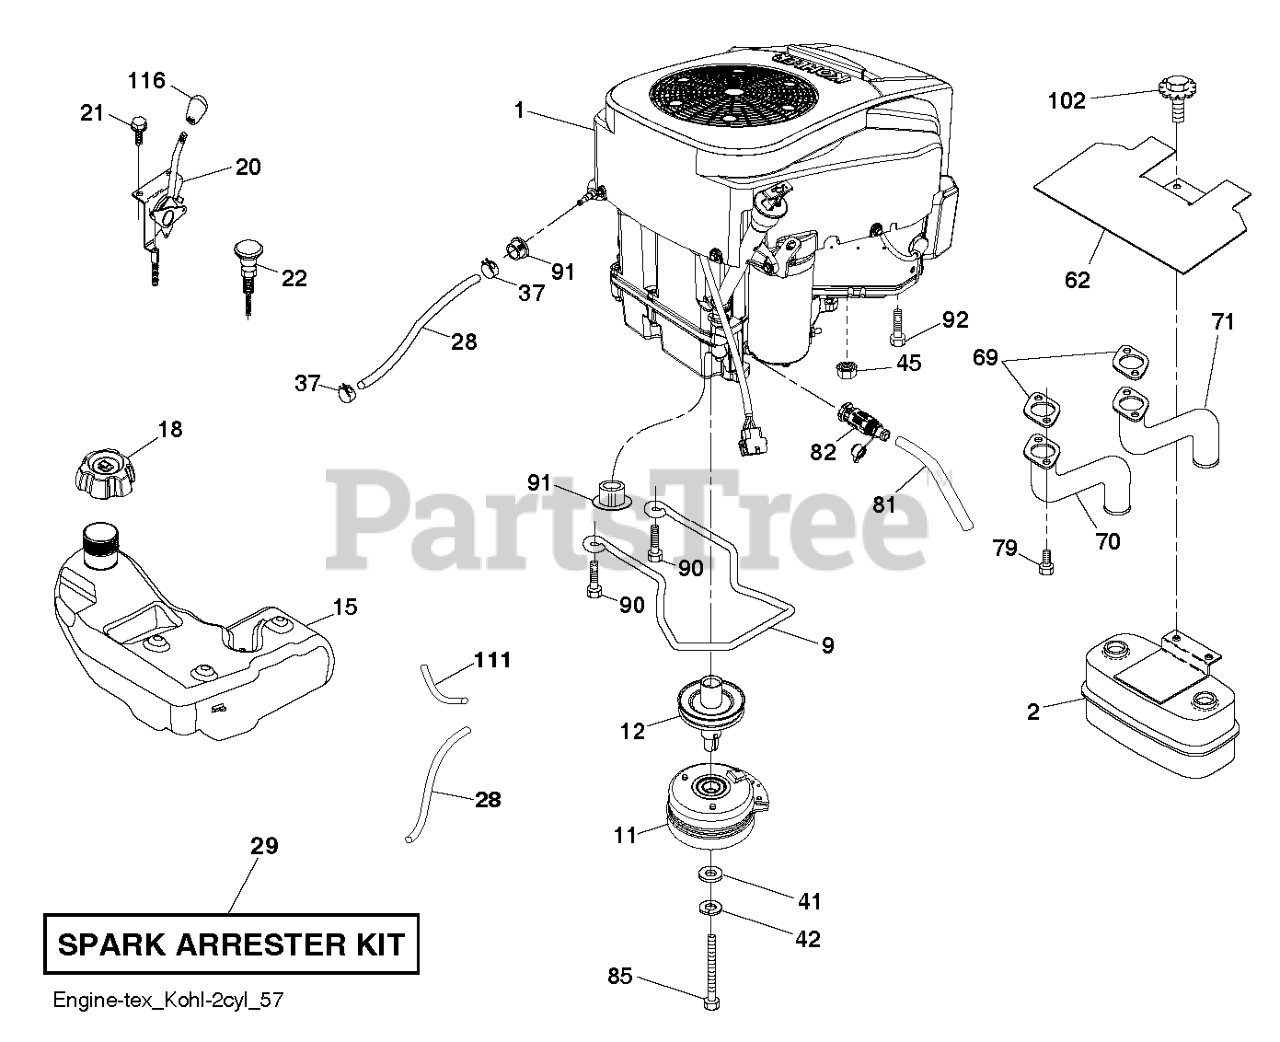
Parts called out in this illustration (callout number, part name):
2	MUFFLER.ASM.TWN.EXTNDED.DFLCTR
9	KEEPER.BELT.ENGINE.4.2
11	CLUTCH. 5.0 PD. 2.5 OFFSET
12	PULLEY.EXTENDED.SHAFT.GROUND
15	TANK.ASM.FUEL.3GA.CARB
18	CAP ASSY FUEL 3" GRAY
20	CONTROL.THROTTLE.PRO.KOHLER
21	SCREW.#10 X 0.750.BOS
22	CONTROL, CHOKE
28	LINE.FUEL.64"REAR.EMIS
29	KIT.SPARK ARRESTOR 794945 B&S
37	HOSE CLAMP
42	LOCKWASHER
45	NUT
62	SHIELD.HEAT.MUFFLER
70	TUBE.EXHAUST.LH.FR961/FR730
71	TUBE.EXHAUST.RH.FR961/FR730
79	SCREW.SOCKET HD.5/16-1
81	TUBE, DRAIN OIL ASM.
82	VALUE.OIL.DRAIN
85	BOLT.HEX.7/16-20 X 5
90	SCREW 3/8-16X1
91	BUSHING.1.375OD
92	SCREW 3/8-16X1
102	SCREW
111	RP PURGE LINE
116	KNOB - SHIFT
